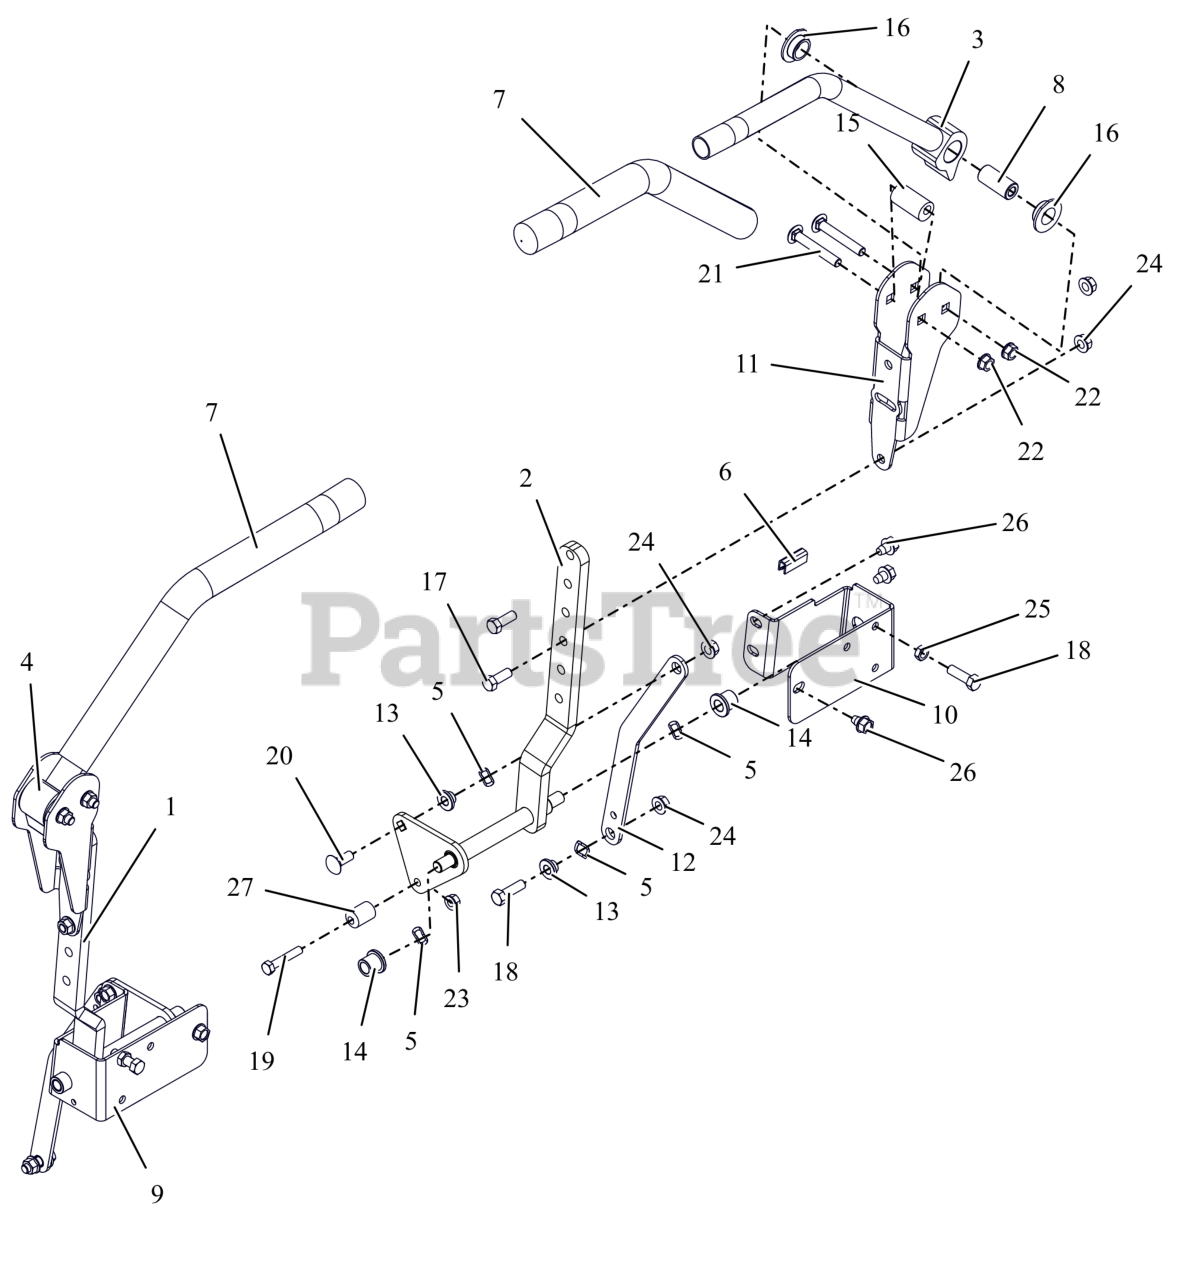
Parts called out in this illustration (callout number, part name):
1	WLDMT, RH LOWER CONTROL ARM (RED)
2	WLDMT, PT100 LH LOWER CONTROL ARM (RED)
3	WLDMT, CONTROL HANDLE-LH (BLACK)
4	WLDMT, CONTROL HANDLE-RH (BLACK)
5	WAVE WASHER .531X.781X.125FH
6	STRIP, COWL
7	GRIP, HANDLEBAR
8	SPACER, STEERING ARM
9	RH PT/PT100 DRV CNTRL STOP-RED
10	LH PT/PT100 DRV CNTRL STOP-RED
11	BRKT, ADJ UPPER CONTROL ARM (RED)
12	LINK, DRIVE CONTROL - BLACK
13	BSHG-FLG .385X.500X.875X.406
14	BHSG-FLG .500X.750X.750X.125
15	BSHG, ECCENTRIC.406X.875X1.625
16	BSHG, FLANGED .762 X 1.48 X .44 IGLIDER
17	BLT,HEX .38-16X1.00 G5 ZCC
18	BLT, HEX .38-16X1.25 G5 ZCC
19	BLT, HEX .31-18X1.75 G5 ZCC
20	BLT, RHSN .38-16X1.00 G5 ZCC
21	BLT, RHSSN.38-16X2.50 G5 ZCC
22	NUT, SPNLK-FLG .38-16 G5 ZCC
23	NUT,LK-CTR-FLG .31-18 GF ZCC
24	NUT-LK-CTR-FLG .375-16 GF ZCC
25	NUT-JAM .375-16 G2 ZCC
26	SCR,TAP .375-16X.50 HWH TR ZCC
27	ECCENTRIC
